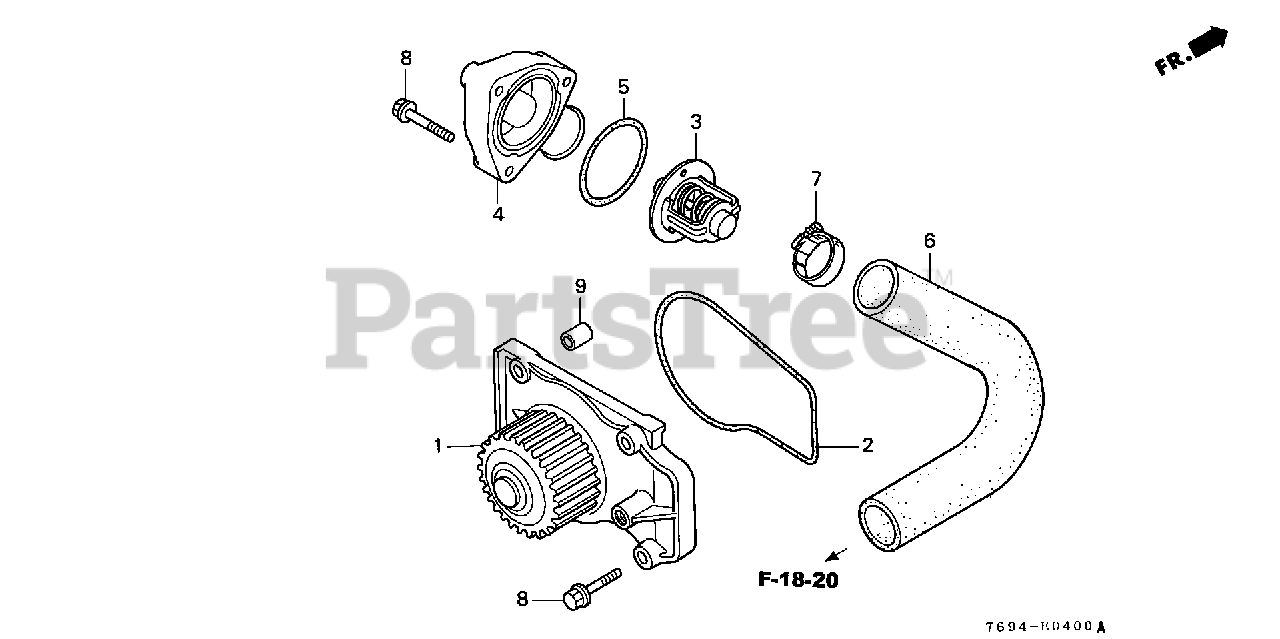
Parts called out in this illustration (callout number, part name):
1	WATER PUMP
2	O-RING, WATER PUMP
3	THERMOSTAT
4	COVER, THERMOSTAT
5	O-RING, THERMOSTAT COVER
6	HOSE B, WATER (LOWER)
7	BAND, WATER HOSE
8	BOLT, FLANGE (6X32)
9	PIN A, DOWEL (8X14)
